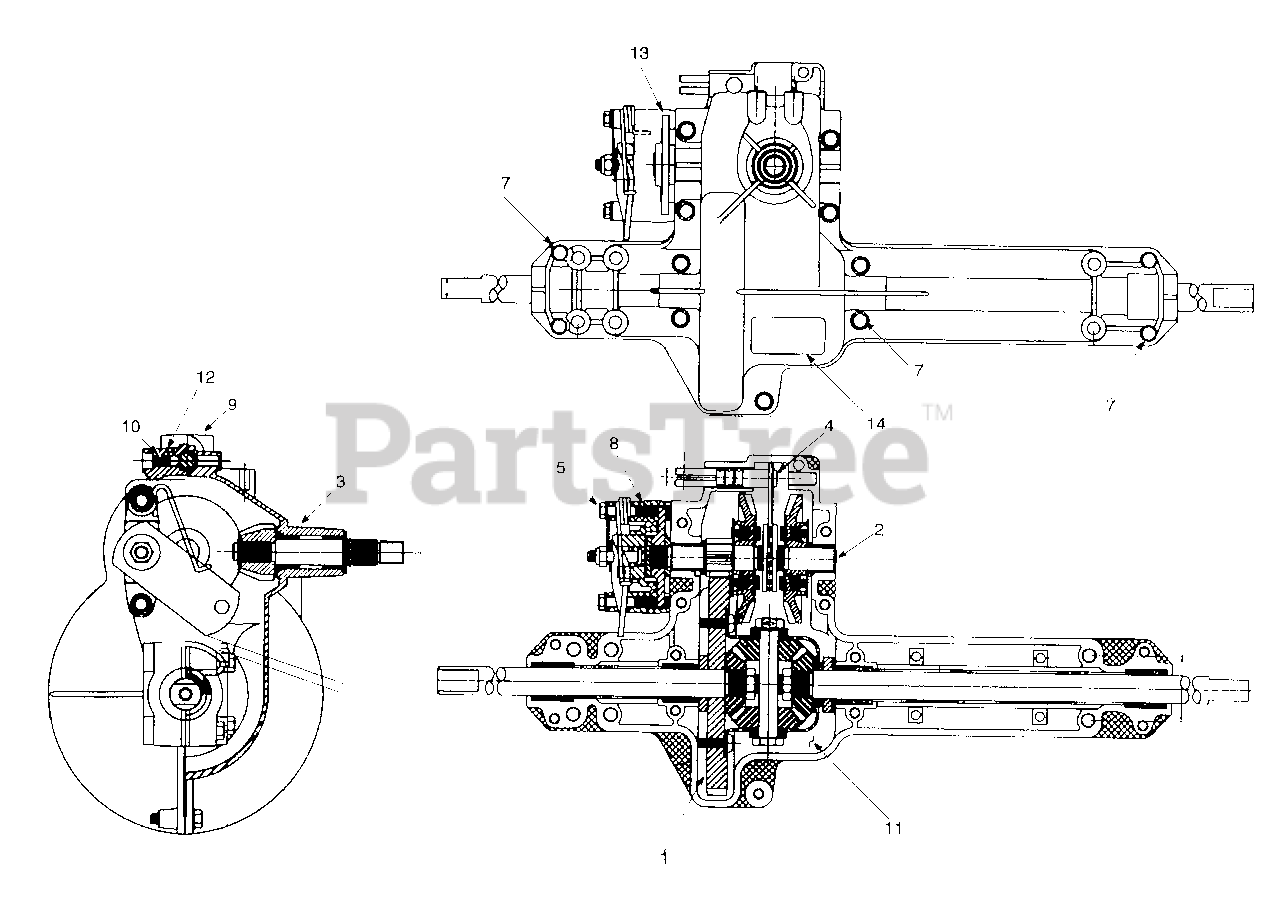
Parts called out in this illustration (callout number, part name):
1	Differential Assembly: Single Speed
2	Drive Shaft Assembly: LH Brake
3	Upper Housing Assembly
4	Detent Shaft Assembly
5	Brake Yoke Assembly: LH
7	Hex Washer Hd. TT Screw 1/4-20 x 1.65
8	Brake Puck
9	Lower Housing
10	Spring Detent
11	Grease
12	Ball Detent
13	Brake Disc
14	Label
